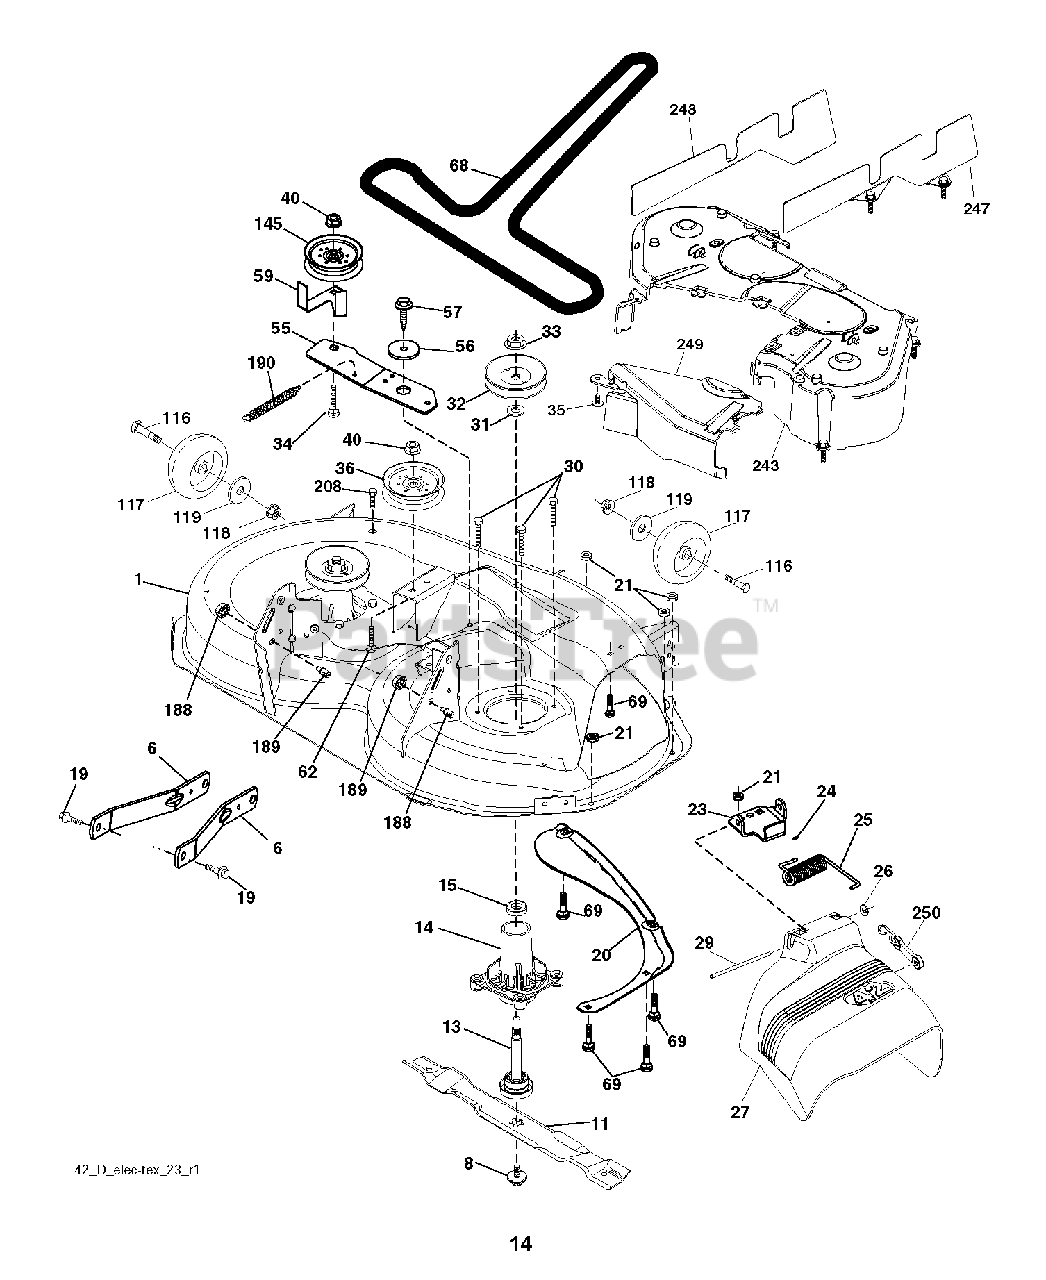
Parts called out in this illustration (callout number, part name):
1	DECK.WELDMENT.42"
6	ARM.SUSPENSION.MOWER.R
8	BOLT.WASHER.ASM.7/16-2
11	42" HI-LIFT BLADE
13	SHAFT.ASM.MDRL.N/GREASE.38
14	HOUSING MANDREL
19	BOLT.SHOULDER
20	BAFFLE.VORTEX
21	LOCKNUT
23	BRKT.DEFLECTOR.38"2005+
24	CAP-SLEEVE LT
25	SPRING.TORSION.DEFLECT
26	NUT PUSH M
29	ROD.HINGE
30	SCREW, WASHER HEAD
31	WASHER.SPACER.MANDREL
32	PULLEY/MANDREL
33	NUT.FLANGE.LOCK.TOP
34	BOLT.3/8-16X1.50
35	FASTENER.XMAS.TREE
36	PULLEY.IDLER.2006
40	NUT LOCK FLG 3/8-16 UNC
55	IDLER.ARM.42"
56	SPACER.RETAINER
57	SCREW 3/8-16X1
59	GUARD, BELT
62	BOLT
68	BELT V SECONDARY
69	BOLT
117	WHEEL.GAGE.HALF.SPOKED
118	NUT LOCK FLG 3/8-16 UNC
119	WASHER
145	PULLEY.IDLER.48"PRIMARY
188	STUD.FASTNER.W/ANTI-ROTATE
189	NUT LOCK HEX FLANGE 5/16-18
190	SPRING.MOWER.DRIVE.ELECTRIC
208	SCREW 3/8-16X1/2
